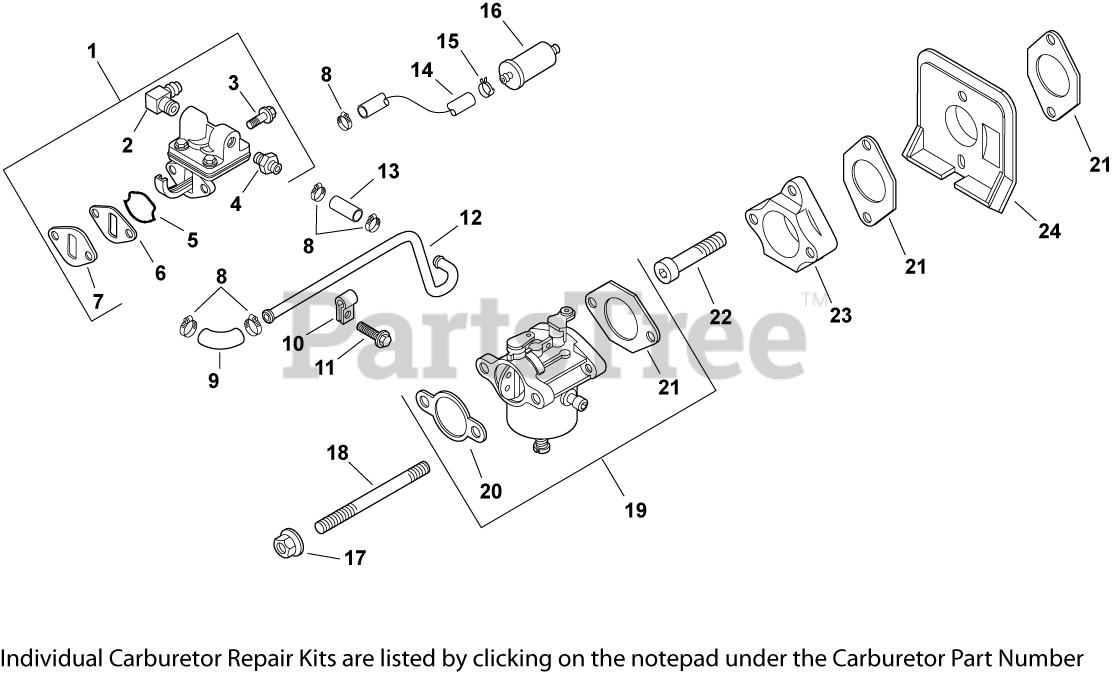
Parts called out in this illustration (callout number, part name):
1	KIT, FUEL PUMP
2	CONNECTOR, 90 DEG. HOSE
3	SCREW,FLG THD FRM M6X1.0X20-(#25086396S)
4	KIT, STRAIGHT FITTING
5	O-RING, FUEL PUMP
6	SPACER, FUEL PUMP
7	GASKET, FUEL PUMP
8	CLAMP, HOSE (KM)-USE 25 237 31-S
9	LINE, FUEL-FLEXIBLE - USE 25 111 36-S
11	SCREW, FLG THD FRM M5X.8X10
12	LINE, FUEL - DISCONTINUED
13	LINE - DISCONTINUED
14	LINE, FUEL
15	CLAMP, BAND SPRING HOSE-(#2523737S)
16	FILTR,FUEL 75 MICRON (GRAVTY FEED)
17	NUT, FLG M6X1.0
18	STUD,M6X1.0X116
19	KIT, CARBURETOR w/GASKETS
20	GASKET, AIR CLEANER BASE
21	GASKET, CARBURETOR
22	SCREW, SKT CAP M6X1.0X35
23	ADAPTER, CARBURETOR
24	DEFLECTOR, HEAT
